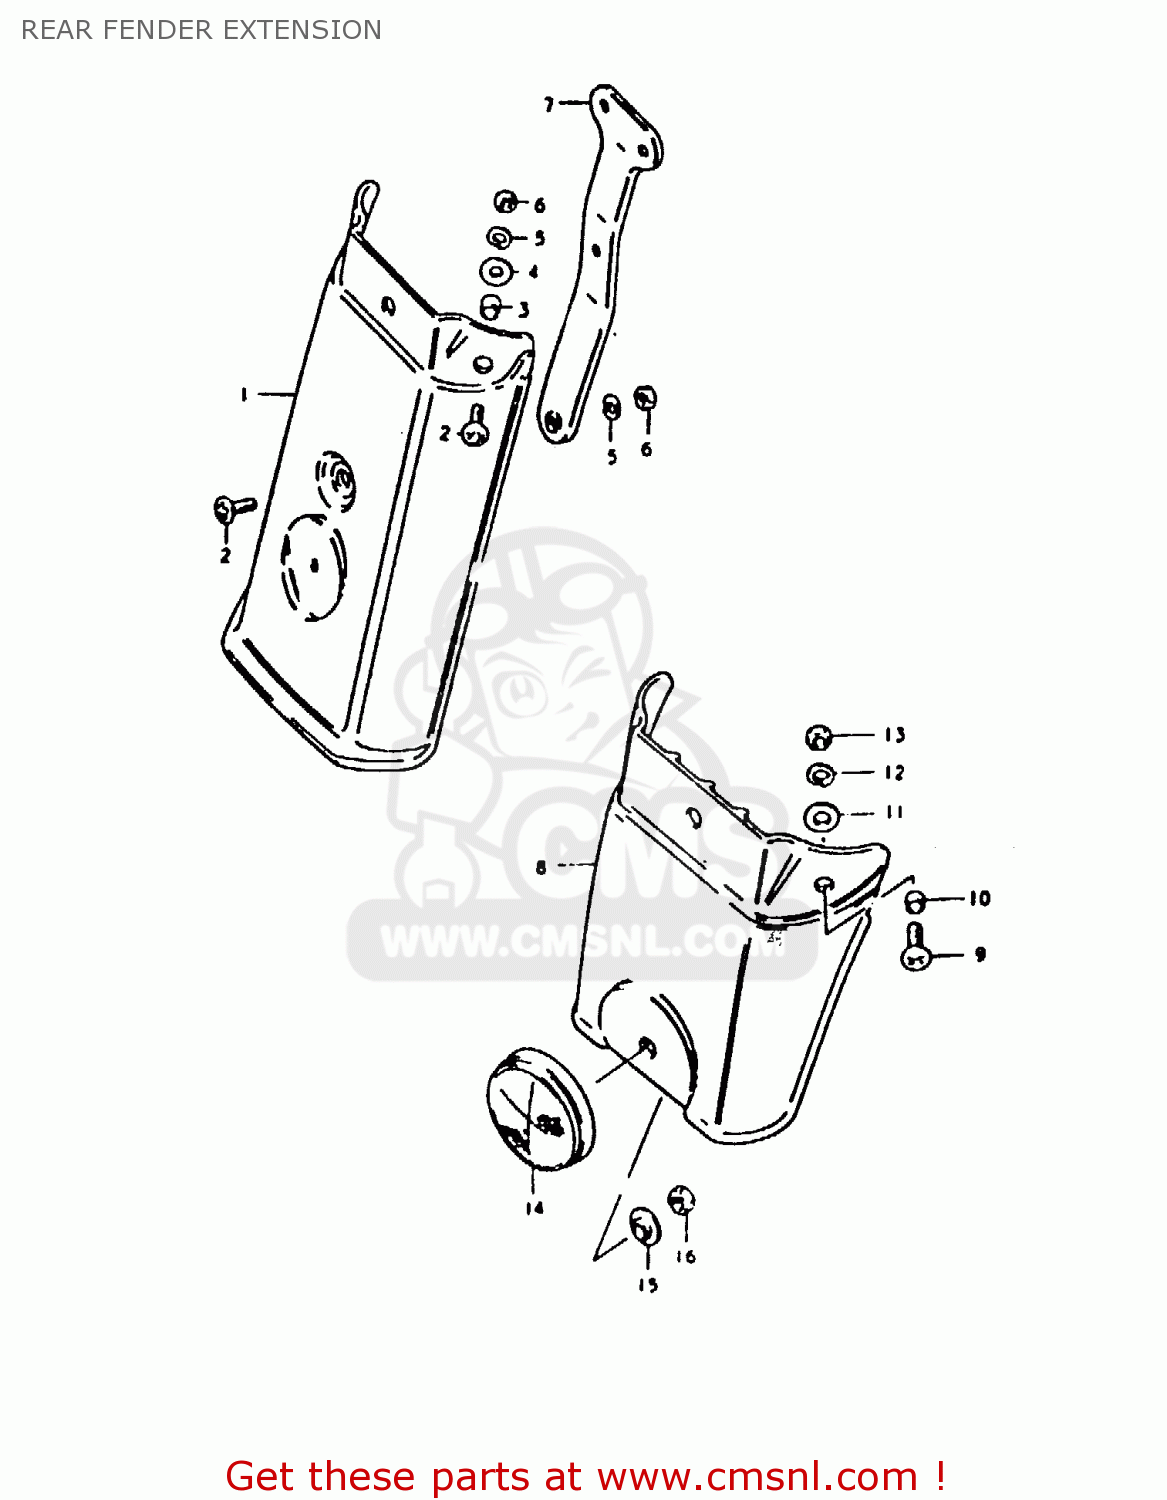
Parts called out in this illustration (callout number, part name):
1	EXTENSION, REAR FENDER
2	SCREW (6X15)
3	SPACER(6.2X8.3X5.7)
4	WASHER(6.5X18X1)
5	LOCK WASHER
6	NUT
7	BRACE, REAR FENDER EXTENSION
8	EXTENSION,REAR FENDER
9	SCREW (6X15)
10	SPACER(6.2X8.3X5.7)
11	WASHER(6.5X18X1)
12	LOCK WASHER
13	NUT
14	REFLECTOR,REFLEX
15	SPACER
16	NUT
